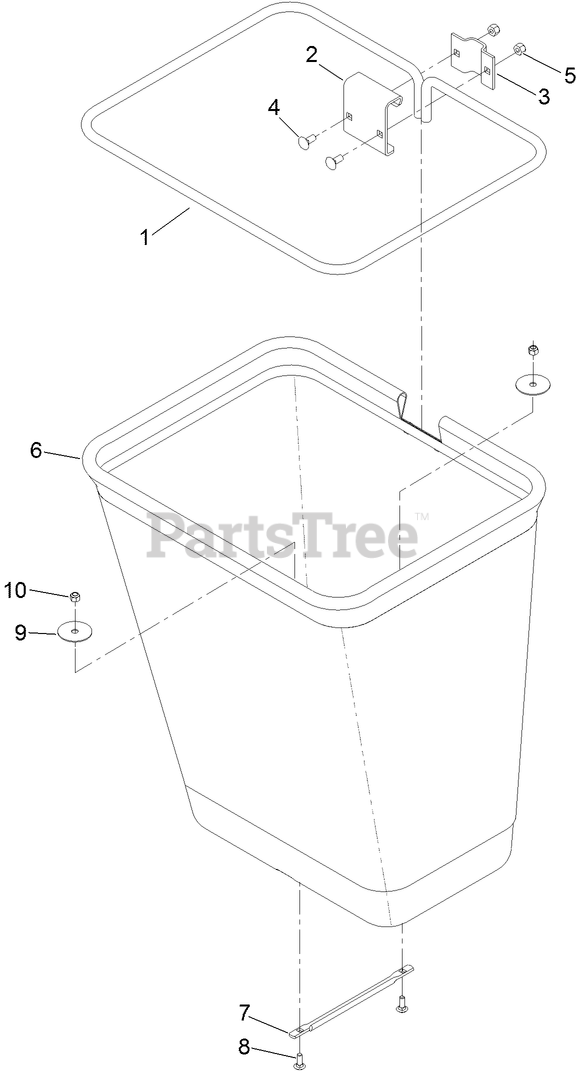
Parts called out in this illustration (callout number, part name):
1	FRAME-BAG
2	HANGER-BAG
4	BOLT-CARR
5	NUT-LOCK, NI
6	BAG ASM
7	HANDLE-BAG
8	BOLT-CARR
9	WASHER
10	NUT-LOCK, NI
